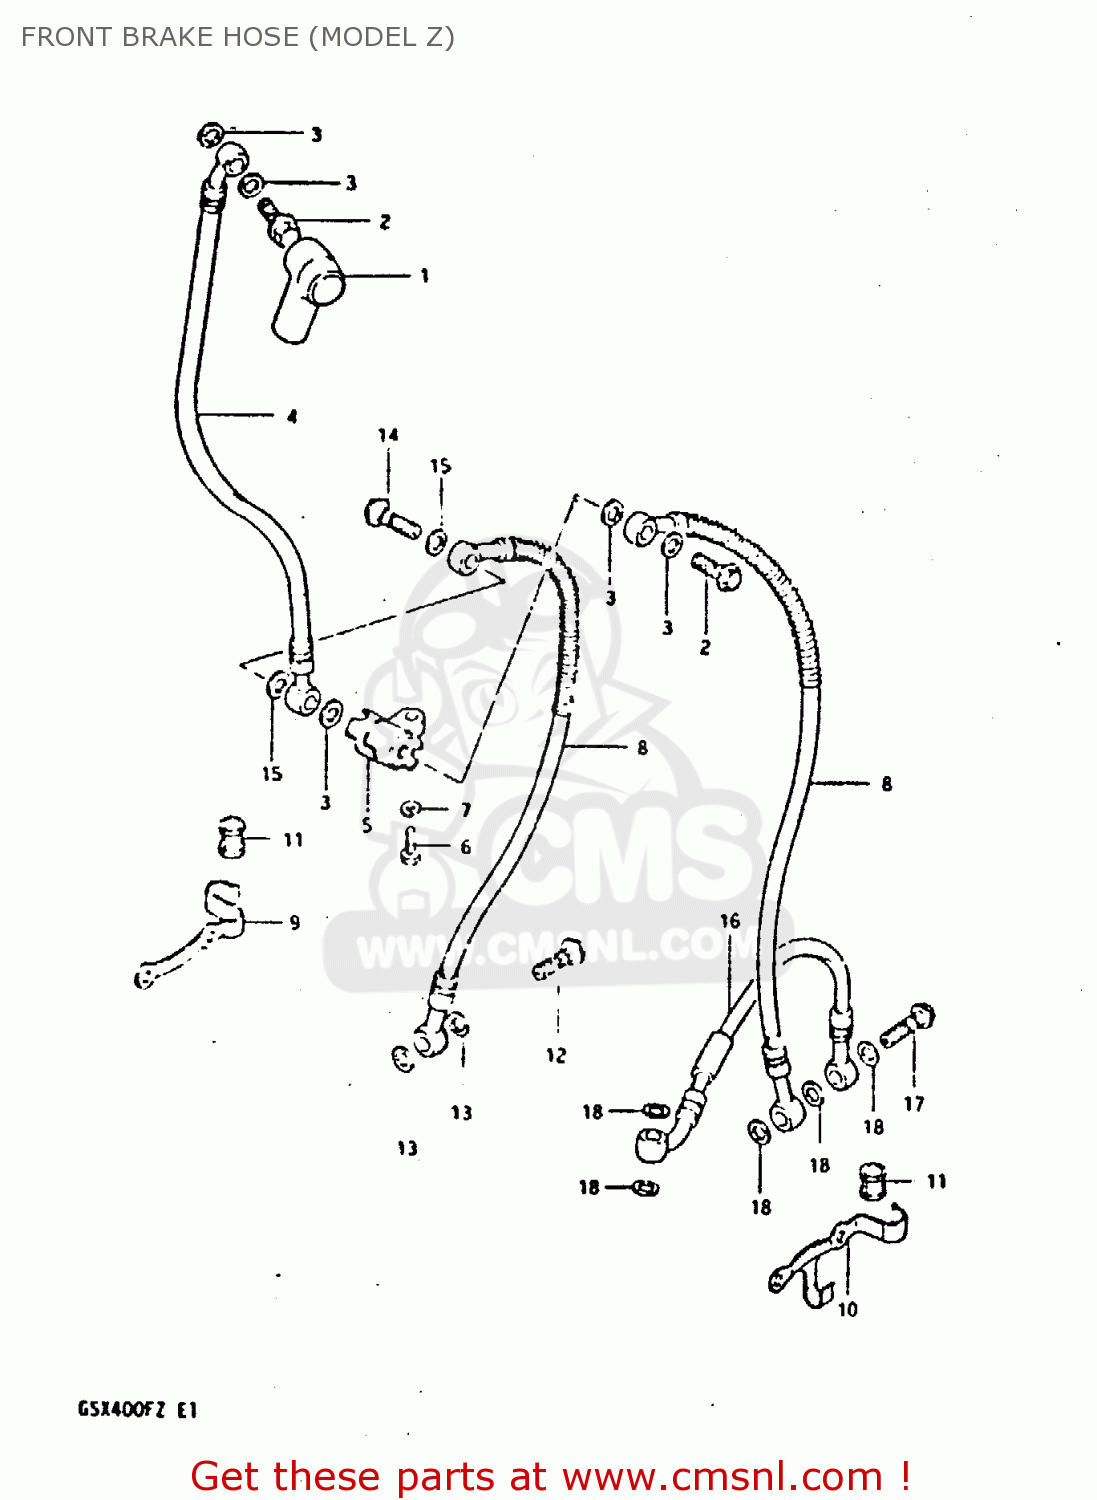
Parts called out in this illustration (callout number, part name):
1	BOOT,MASTER CYLINDER
2	BOLT,UNION
3	WASHER
4	HOSE,FRONT BRAKE
5	JOINT,BRAKE HOSE
6	BOLT
7	LOCK WASHER
8	HOSE,BRAKE NO.2
9	GUIDE,BRAKE HOSE NO.2
10	CLAMP, HOSE LH
11	BUSH,BRAKE HOSE GUIDE,NO.2
12	BOLT,UNION
13	WASHER
14	BOLT,UNION
15	WASHER
16	HOSE, ANTINOSE DIVE
17	BOLT,UNION
18	WASHER
